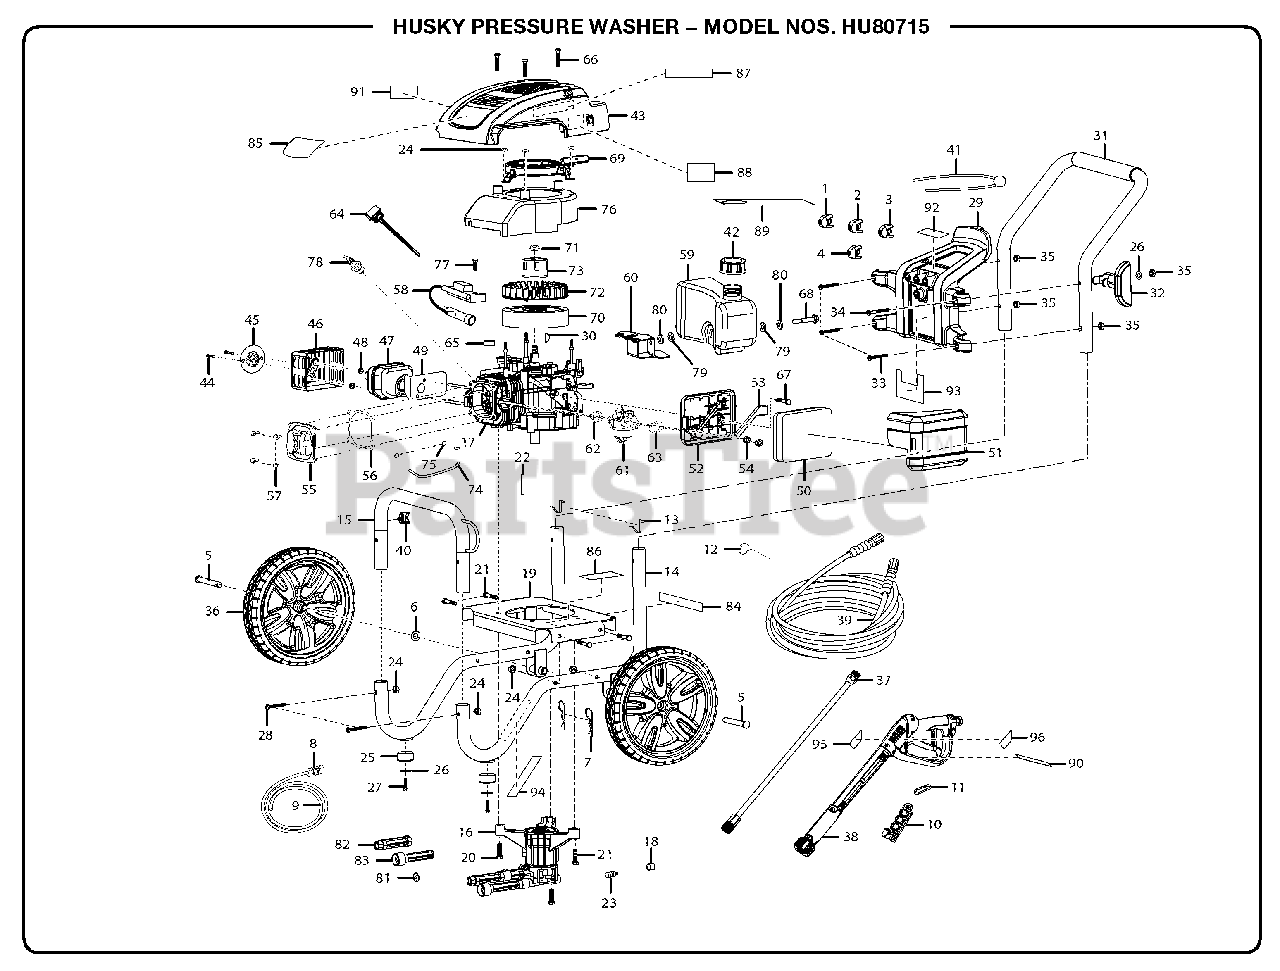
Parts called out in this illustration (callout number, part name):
1	0° Nozzle
2	15° Nozzle
3	25° Nozzle
4	Detergent Nozzle
5	Axle
6	Washer (1/2 in.)
7	Hitch Pin
9	Injection Hose
10	Storage Holder
11	Spring Clip
12	Nozzle Cleaning Tool
13	Lock Button w/Spring Clip
14	Main Frame Assembly
15	Front Frame
16	Pump
17	Engine (173cc)
18	TRV Spout
19	Engine Plate
20	Bolt (M8 x 66 mm)
21	Bolt (M8 x 50 mm)
22	Output Shaft Key
23	Thermal Release Valve
24	Lock Nut (M8)
26	Washer (1/4 in.)
27	Bolt (1/4-20 x 1 in., Hex Hd.)
28	Bolt (M8 x 45 mm)
29	Hose and Nozzle Holder
30	Flywheel Key
31	Handle Assembly
32	Wand Holder
33	Screw (1/4-20 x 1.85 in., Torx)
34	Screw (1/4-20 x 2.27 in., Torx)
35	Lock Nut (1/4-20)
36	Wheel (12 in. x 2 in.)
37	Spray Wand
38	Trigger Handle Assembly
39	High Pressure Hose
40	Injection Hose Holder
41	Bungee Cord and Bead Assembly
43	Shroud Assembly w/Switch
44	Screw (M6 x 12 mm)
45	Spark Screen
46	Muffler Cover
48	Hex Nut (M6)
49	Heat Shield
50	Air Filter
51	Air Filter Cover
52	Air Filter Bracket
53	Air Filter Cleaner Breather Cover
54	Hex Nut (M6)
55	Valve Cover
56	Valve Cover Gasket
57	Bolt (M6 x 12 mm)
58	Ignition Module
59	Fuel Tank Assembly
60	Fuel Tank Bracket
61	Carburetor
62	Carburetor Gasket
63	Air Cleaner Gasket
64	Oil Dipstick
65	Spacer Block
66	Screw (M6 x 20 mm)
67	Screw (M6 x 12 mm)
68	Bolt
69	Recoil Starter Assembly
71	Flywheel Nut
73	Starter Pulley
74	Fuel Line
75	Fuel Line Clip
76	Inner Blower Housing Assembly
77	Screw (M6 x 25 mm)
78	Spark Plug
80	Washer
81	Filter Screen
82	Inlet Tube
83	Outlet Tube
84	Data Label
85	Engine Shroud Label
86	Warning Label
87	Engine Quick Start Label
88	Choke Label
89	Engine Oil Fill
90	Wand Label
91	Hot Muffler Label
92	Nozzle Label
93	Performance Label
94	Pump Quick Start Label
95	Trigger Handle Warning Label
96	Trigger Handle Logo Label
